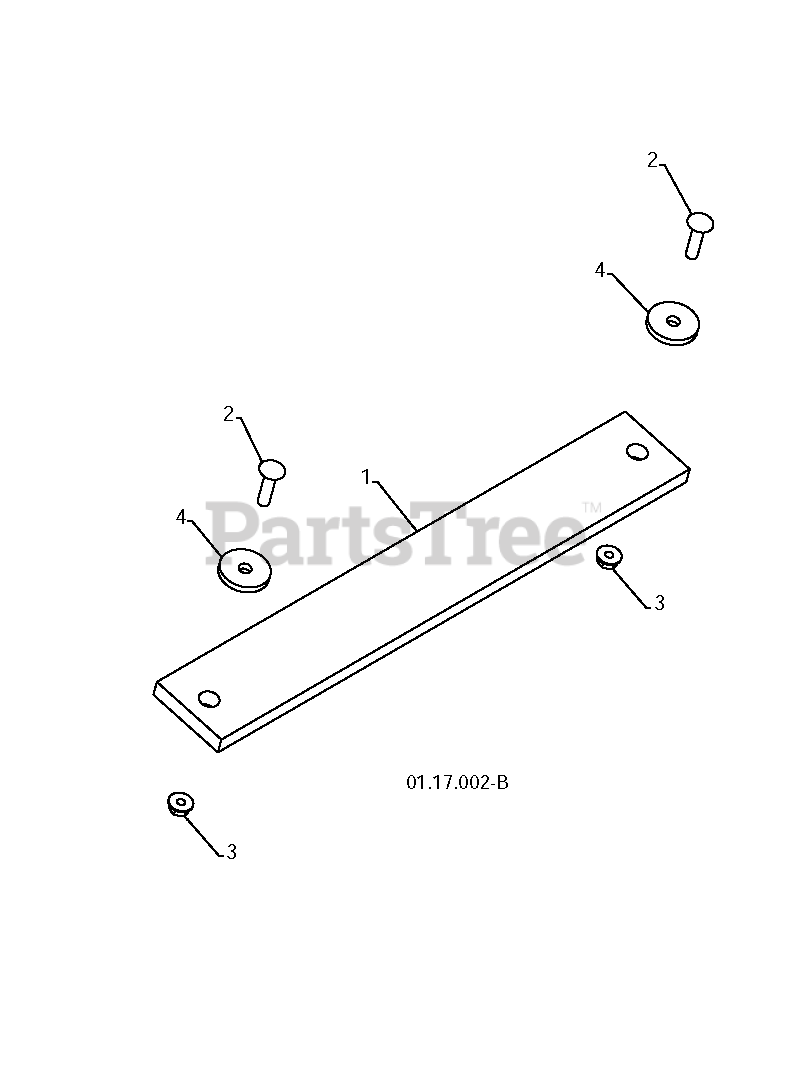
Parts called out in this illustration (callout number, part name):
1	WEIGHT, AUGER HOUSING 27
2	BOLT.CARRIAGE.5/16-18
3	NUT, LOCK 5/16-18
4	WASHER.FLAT.34X1.38X22
